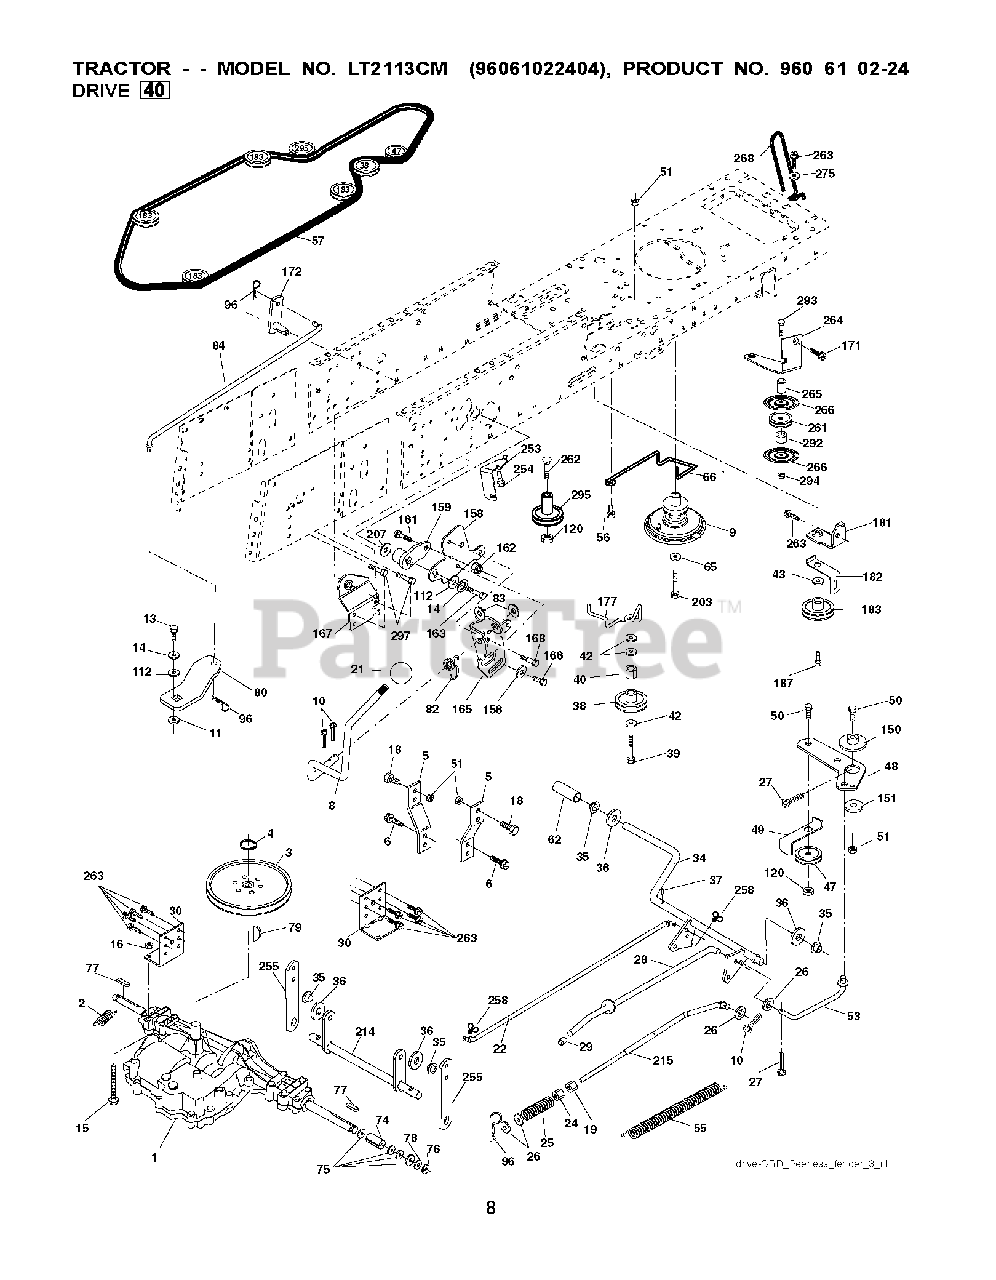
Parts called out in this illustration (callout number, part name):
2	SPRING,BRAKE RETURN
4	RETAINING RING LT
5	STRAP TORQUE
6	SCREW 5/16"
8	ROD SHIFT FENDER ADJUST LT
10	PIN COTTER
11	WASH-SHFT PLT LT
13	BOLT 1/4-28X3/4
14	LOCKWASHER
16	NUT.71038.31-18.HEX.NYLOCK
19	NUT
21	KNOB T (1/2-HOLE)
24	NUT
25	SPRING ROD LT
27	COTTER PIN
28	ROD, PARKING BRAKE
29	PLUNGER CAP
30	BRKT, MOUNT TRNSAXLE
34	SHAFT, FOOT PEDAL
35	BEARING.NYLON
36	WASHER LT
37	DRIVE PIN
38	PULLEY.FLAT
42	WASHER
47	IDLER PULLEY
48	BELLCRANK, CLUTCH
49	RETAIN BELT
50	BOLT.3/8-16X1.50
51	LOCKNUT
53	LINK.CLUTCH.7.66.2005
55	SPRING, RETURN LT
56	SCREW.3/8-16
57	V-BELT.KEV.111"
62	PEDAL COVER T
65	LOCKWASHER
66	KEEPER BELT ENGINE
74	SPACER AXLE
76	E-RING LT
77	SQUARE KEY
80	ARM SHIFT
82	SHIFT SPRING
83	WASHER
96	RETAINER M
112	WASHER LT
120	NUT LOCK FLG 3/8-16 UNC
150	BUSHING.BELLCRANK.GRD.DR
151	WASHER 12/32X2X10GA
156	WASHER.SRRTD.5/16
158	BRACKET.SHIFT.MOUNT
159	HUB.SHIFT
161	BOLT
162	NUT.CROWNLOCK.1/4
165	BRACKET.PIVOT.LEVER
167	BRACKET
168	BOLT.SHOULDER.5/16-18X
183	PULLEY.V-IDLER.
187	BOLT.5/16-18X1.25
207	WASHER NYL
254	SCREW 3/8-16X1
258	CLIP RETAINER
261	FLAT IDLER PULLEY
263	SCREW, 3/8-16X3/4
275	WASHER
294	NUT, HEX 3/8-16
295	PULLEY IDLER COMPOSITE
297	SCREW LT.3/8-46X5/8
